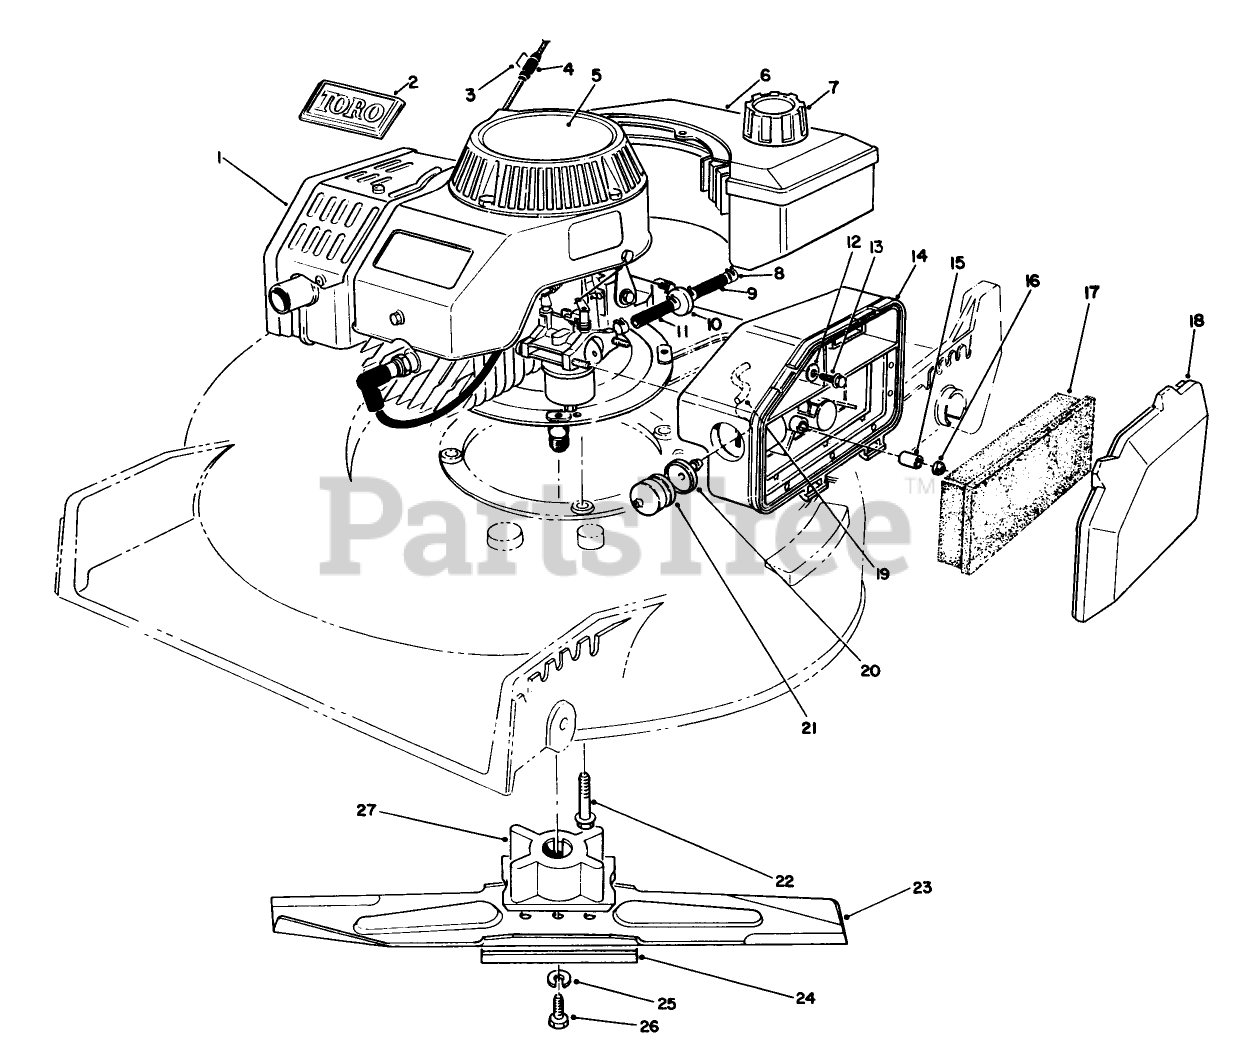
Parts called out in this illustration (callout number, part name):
3	Staple
7	GAS CAP ASM
8	CLAMP-FUEL LINE
9	HOSE-FUEL
10	FILTER-FUEL
11	HOSE-FUEL
12	WASHER-FLAT
13	SCREW-HH
15	SPACER
17	ELEMENT-AIR CLEANER
18	COVER-AIR CLEANER
19	HOSE-PRIMER F
20	BODY-PRIMER
21	BULB-PRIMER
22	SCREW-HHF
25	WASHER-LOCK
26	SCREW-BLADE
27	BLADE RETAINER
